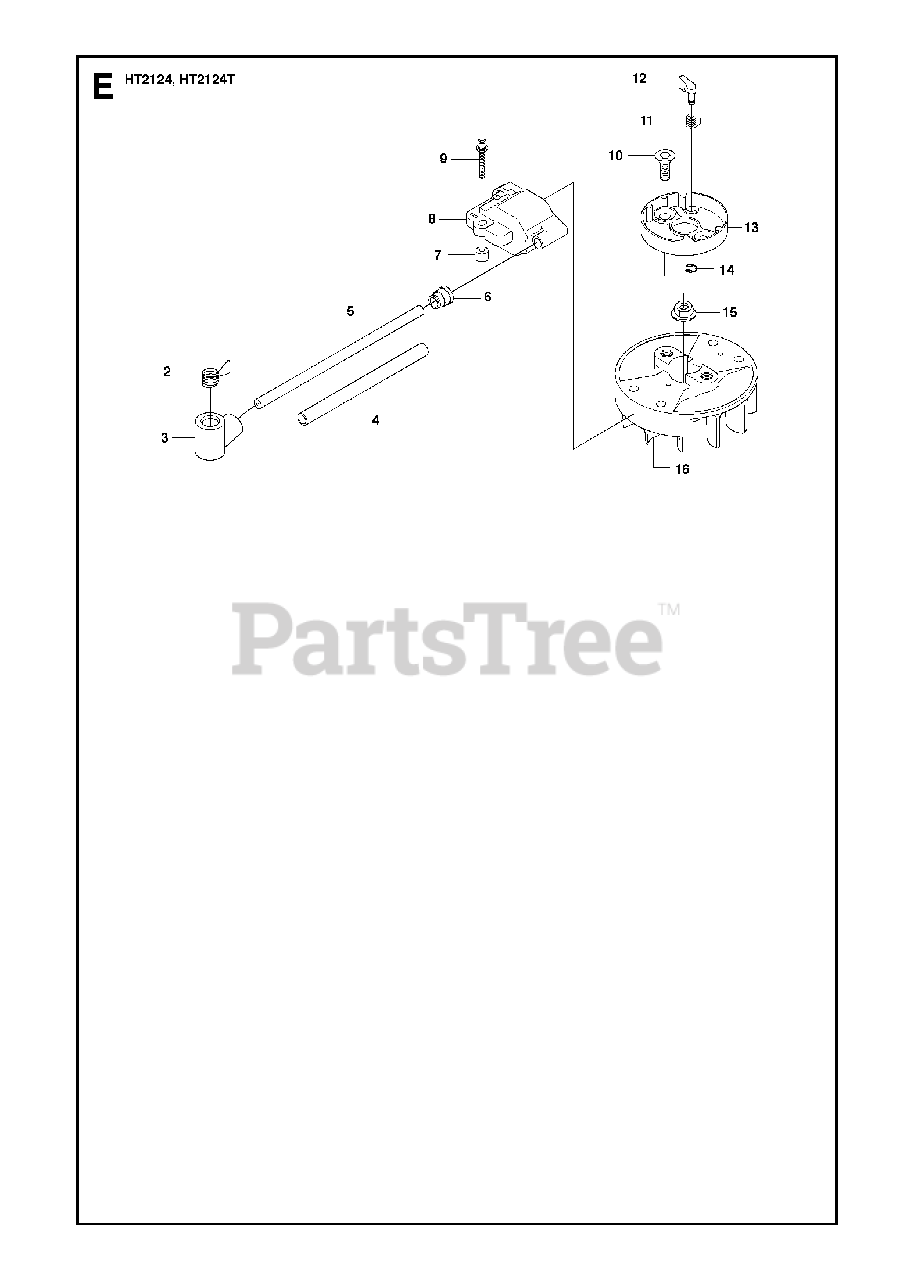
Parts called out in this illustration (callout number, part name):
3	SPARK PLUG CONNECTION
4	INSULATOR
8	IGNITION MODULE
11	RETURN SPRING
14	RETAINING RING
